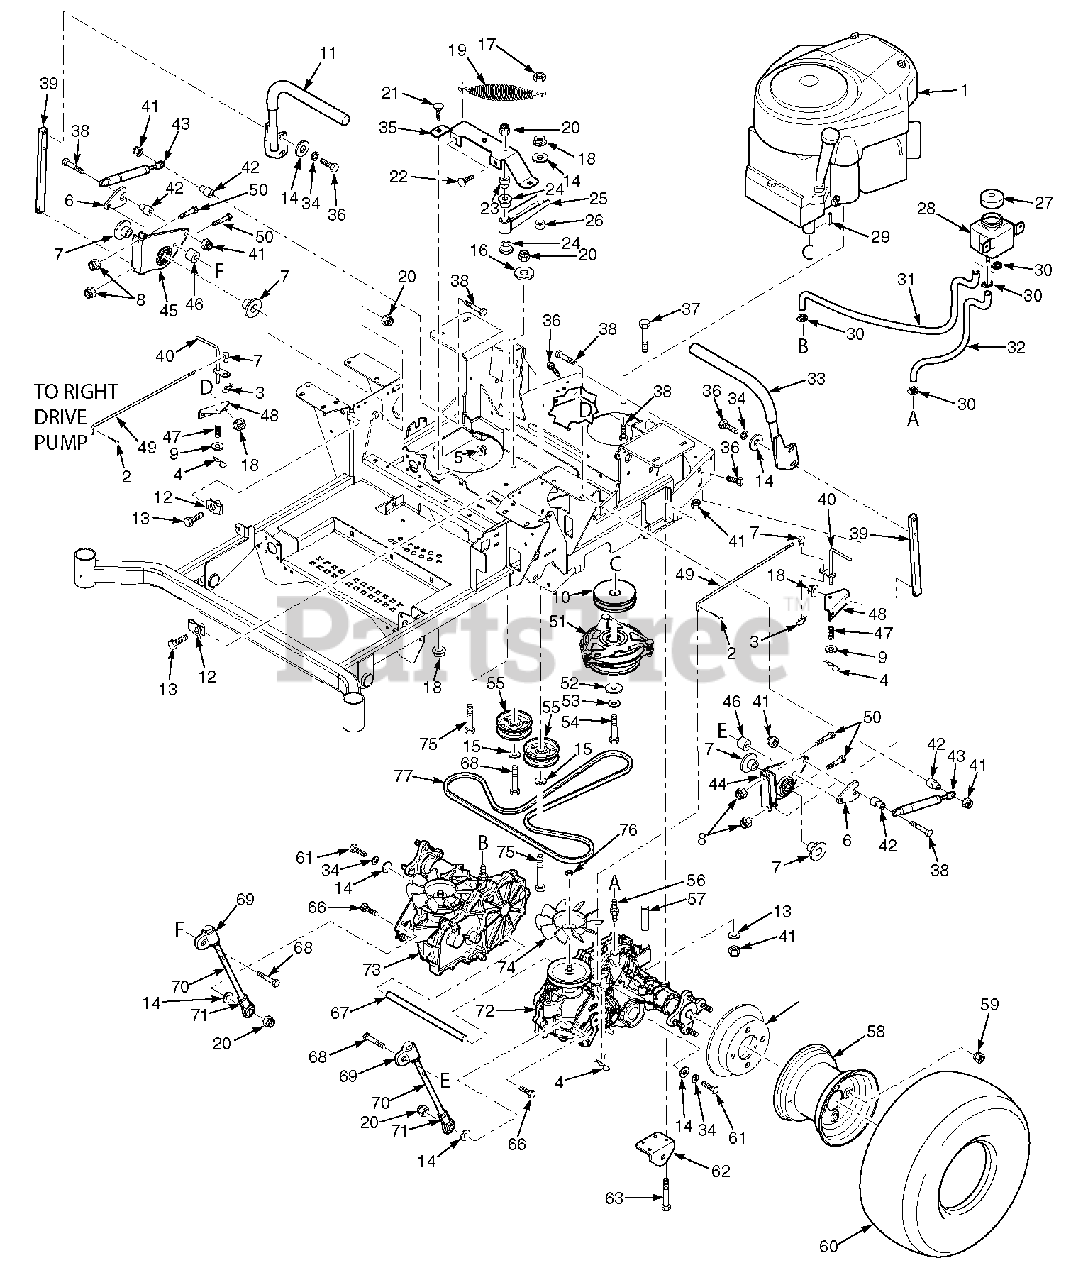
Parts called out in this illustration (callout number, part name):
1	Engine, Briggs & Stratton - 25HP Pro
1	Engine, Kawasaki - 23FS
1	Engine, Briggs & Stratton - 27HP Pro
1	Engine, Kawasaki - 24FS
2	Cotter Pin, 3/32 x 1"
3	Pin, Rue Cotter 3/8" Dia.
4	Hair Pin, .080 x 1.19"
5	Nut, Serrated Flange 5/16-18
6	Nut, Control Link
7	Spacer, Linkage
8	Nut, Elastic Stop 1/4-20
9	Flatwasher, 1/4-.312 x .750 x .065
10	Pulley, 5" OD - 1.125 Bore (SFZ52)
10	Pulley, 4-1/2" OD - 1.125 Bore (SFZ61)
11	Handle Bar w/Grip
12	U-Nut, 3/8-16
13	Bolt, Hex Head 3/8-16 x 1-1/4" Special
14	Flatwasher, 3/8-.391 x .938 x .105
15	Flatwasher, 3/8-.391 x .938 x .105 HD
16	Flatwasher, 3/8-.406 x 1.5 x 7 GA.
17	Nut, Center Lock 3/8-16
18	Nut, Serrated Flange 3/8-16
19	Spring, Transmission Idler
20	Nut, Elastic Stop 3/8-16
21	Bolt, Carriage 3/8-16 x 3/4"
22	Bolt, Carriage 5/16-18 x 3/4"
23	Shaft Pivot, Idler Arm
24	Bearing
25	Transmission Idler Arm Assembly
26	Spacer, Idler Pulley - SFZ52
26	Spacer, Idler Pulley - SFZ61
28	Reservoir Assembly
29	Key, 1/4 x 1/4 x 2-3/4"
30	Clamp, 0.87" Max Dia.
31	Hose, RH Transmission
32	Hose, LH Transmission
33	Handle Bar Assembly, w/Grip
34	Lockwasher, 3/8" Spring
35	Support, Idler Arm
36	Bolt, Hex Head 3/8-16 x 1"
37	Bolt, Hex Head 5/16-18 x 5"
38	Bolt, Hex Head 5/16-18 x 1-1/2"
39	Bar, Control Lever
40	Dump Valve Lever
41	Nut, Elastic Stop 5/16-18
42	Spacer, Pump Dampener
43	Dampener
44	Control Link, LH
45	Control Link, RH
46	Spacer
47	Spring
48	Bracket, Dump Mounting
49	Linkage, Dump Valve
50	Bolt, Hex Head 1/4-20 x 1-1/2"
51	Electric Clutch Assembly - SFZ52 & SFZ61
52	Flatwasher, 7/16-.469 x 1.75 x .25
53	Lockwasher, 7/16" spring
54	Bolt, Hex Head 7/16-20 x 1-1/2" Patch SFZ-61
55	Pulley, 3-1/2" Dia.
56	Fitting, Transmission - SFZ52
56	Fitting, Transmission - SFZ61
57	Spacer, Axle - SFZ52
57	Spacer, Axle - SFZ61
58	Rim w/Valve Stem (52)
58	Rim w/Valve Stem (61)
59	Wheel Nut, 1/2-20
60	Wheel Assembly, 22 x 9.5-12 (SFZ52)
60	Tire, 22 x 9.5-12 (SFZ52)
60	Rim (SFZ52)
60	Wheel Assembly, 23 x 9.5-12 (SFZ61)
60	Tire, 23 x 9.5-12 (SFZ61)
60	Rim (SFZ61)
61	Bolt, Hex Head 3/8-16 x 2-1/4"
62	Bracket, Pusharm Link
63	Bolt, Hex Head 5/16-18 x 3"
64	Clip, Brake Lever (order through Hydro-Gear)
65	Lever, Brake (order through Hydro-Gear)
66	Bolt, Hex Head 3/8-16 x 1-1/4"
67	Spacer, Axle
68	Bolt, Hex Head 3/8-16 x 2"
69	Rod End, Adjustable 3/8-24
69	Nut, Jam 3/8-24 UNF RH
70	Linkage, Pump - SFZ52
70	Linkage, Pump - SFZ61
71	Stake, Rod End Assembly
72	Transaxle Assy., LH (ZL-KCEF-3LKG-1NXX) SFZ52
72	Transaxle Assy., LH (ZS-KCEE-3LKG-11XX) SFZ61
72	Transaxle Assy., RH (ZL-GCEF-3LKG-1NXX) SFZ52
73	Transaxle Assy., RH (ZS-GCEE-3LKF-11XX) SFZ61
74	Fan (order through Hydro-Gear)
75	Bolt, Hex Head 3/8-16 x 3"
76	Fan Nut (order through Hydro-Gear)
77	Belt, Transmission Drive - SFZ52
77	Belt, Transmission Drive - SFZ61
